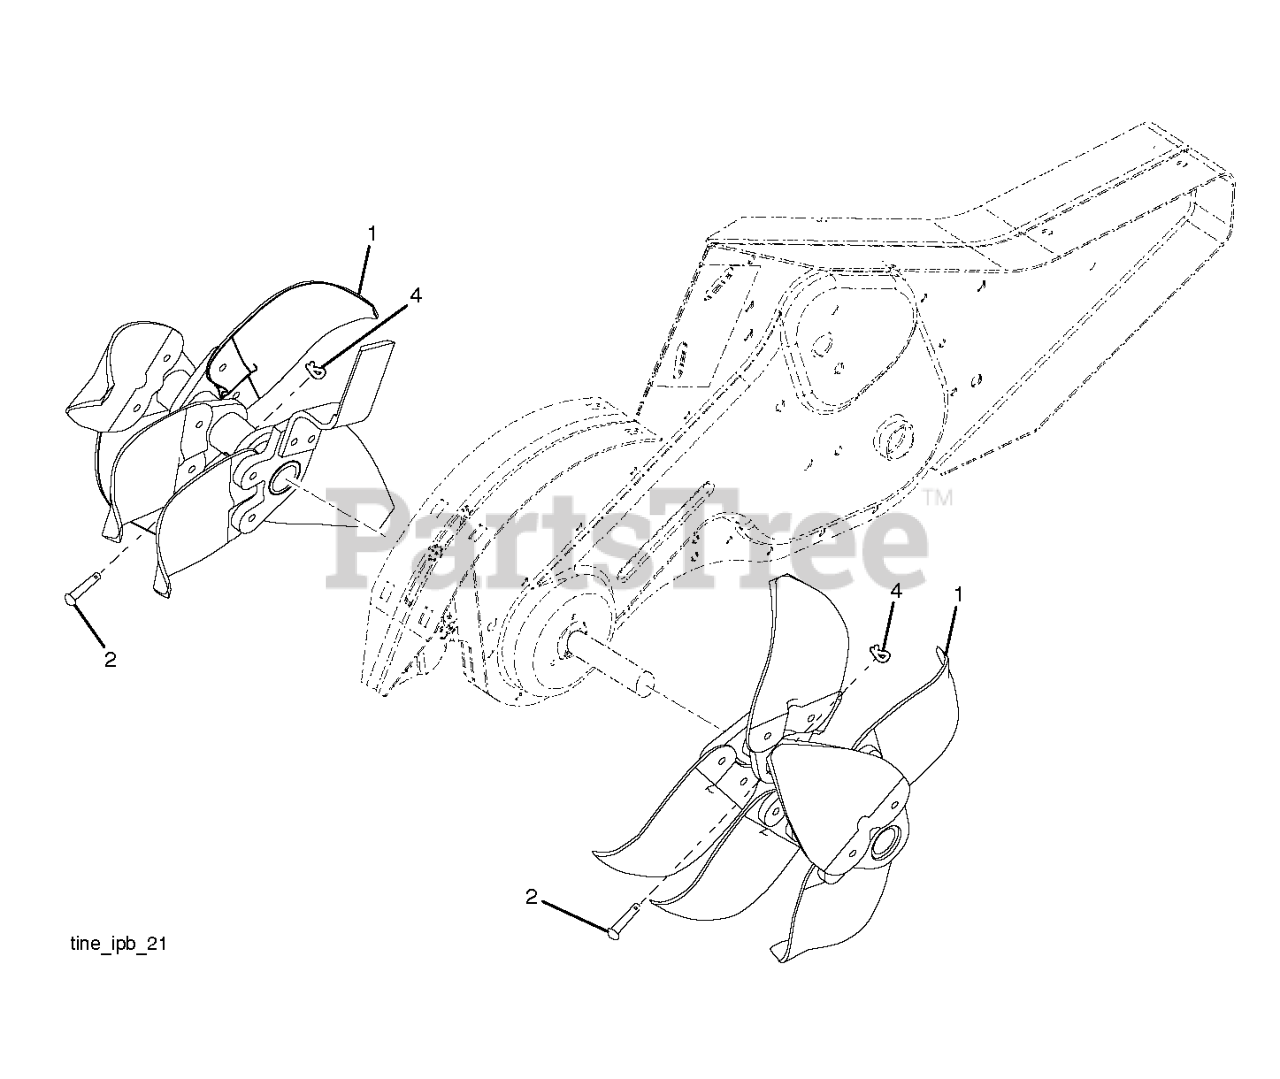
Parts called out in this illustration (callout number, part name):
1	TINE.ASM.DRT TILLER.479
2	PIN RETAINING SCREW
4	SPRING RETAINER
